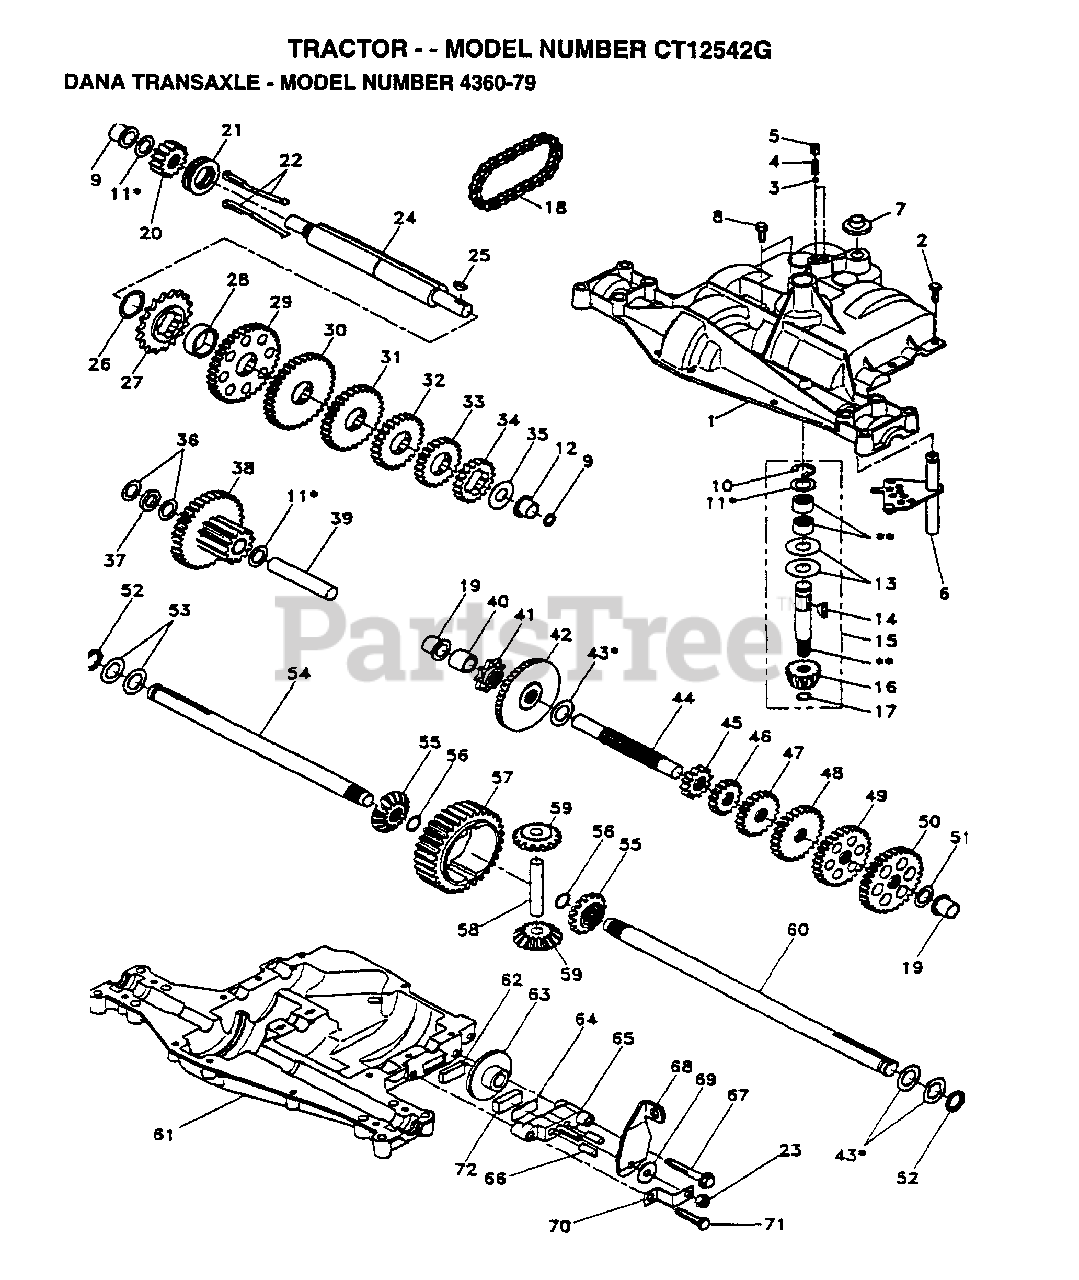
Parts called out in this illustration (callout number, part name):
1	HOUSING UPPER TRN
4	"SPRING, DETENT LT"
5	"SCREW, SET LT"
6	KIT SHIFTER ASM
7	SHIFTER BOOT
8	SCREW TAP W/SEAL
9	SQUARE RING
11	ASM KIT SHIM 4689
12	BEARING FLAN-DANA
13	WASHER T
14	KEY WOODRUFF-DANA
15	AS KIT INPUT SHFT
16	PINION 14T T
17	"RING,RETAINING LT"
18	"CHAIN,24 PTCH LT"
19	BEARING.FLNG.5510
20	GEAR SPUR 14 TTH
21	COLLAR CLUTCH
22	ASM KIT CLTCH KEY
23	NUT.LOCK.5/16-24
24	SHAFT INTERM DANA
25	WOODRUFF KEY
26	"RING,RETAINING LT"
27	SPROCKET 18T T
28	SPACER YT
29	GEAR SPUR 37 TTH
30	GEAR SPUR 35 TTH
32	GEAR 25T LT
33	GEAR SPUR 22 TT
34	SPUR GEAR 19T
35	"WASHER, PLAIN LT"
36	WASHER 025
37	SPACER
38	ASSM GEAR COMB
39	SHAFT IDLER
40	SPACER T
41	SPROCKET 9T LT
43	ASM KIT SHIM
44	SHAFT T
45	GEAR SPUR 12 TTH
46	GEAR SPUR 15 TTH
48	"GEAR, SPUR 25T LT"
49	GEAR 28T T
50	"GEAR, SPUR 31T LT"
51	WASHER 060
52	NEOPRENE WASHER
53	WASHER 031
55	GEAR 15T T
56	"RING,RETAINING LT"
58	SHAFT T
59	GEAR 1ST T
61	HOUSING LOWER TNS
62	PUCK T
63	BRAKE DISC. T
64	SPACER LT
66	PIN T
69	WASHER LT
71	"SCREW, TAPPING LT"
72	PUCK T
